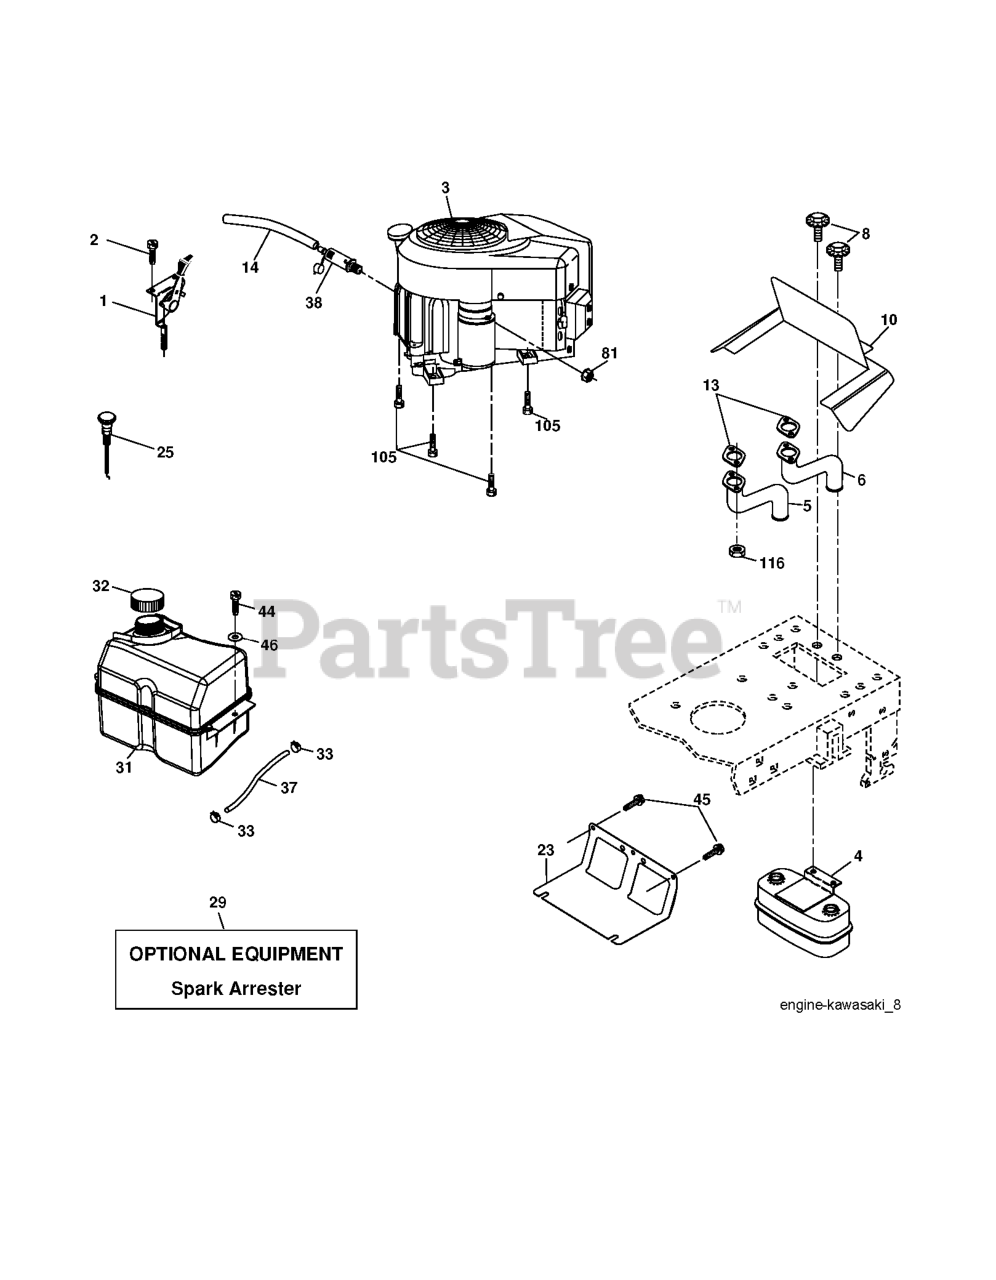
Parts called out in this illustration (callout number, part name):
1	CONTROL, THROTTLE
2	SCREW
4	MUFFLER.TWIN.CYL.LOW.TONE
5	EXHAUST TUBE RH KAWI
6	EXHAUST TUBE LH KAWI
8	BOLT.5/16-18UNCX3/4 W/SEMS.BLK
10	RP SHIELD HEAT MUFFLER
14	TUBE, DRAIN OIL ASM.
23	SHIELD.BROWNING.DBR.GUARD
29	KIT.SPARK ARRESTOR 794945 B&S
31	TANK FUEL
32	FUEL CAP
33	HOSE CLAMP
37	LINE.FUEL.20
44	SCREW HEXWSHR 1/4-20X3/4
45	SCREW, 3/8-16X3/4
81	NUT
105	SCREW 3/8-16X1
116	NUT.HEX.FLANGE.TOPLOCK
